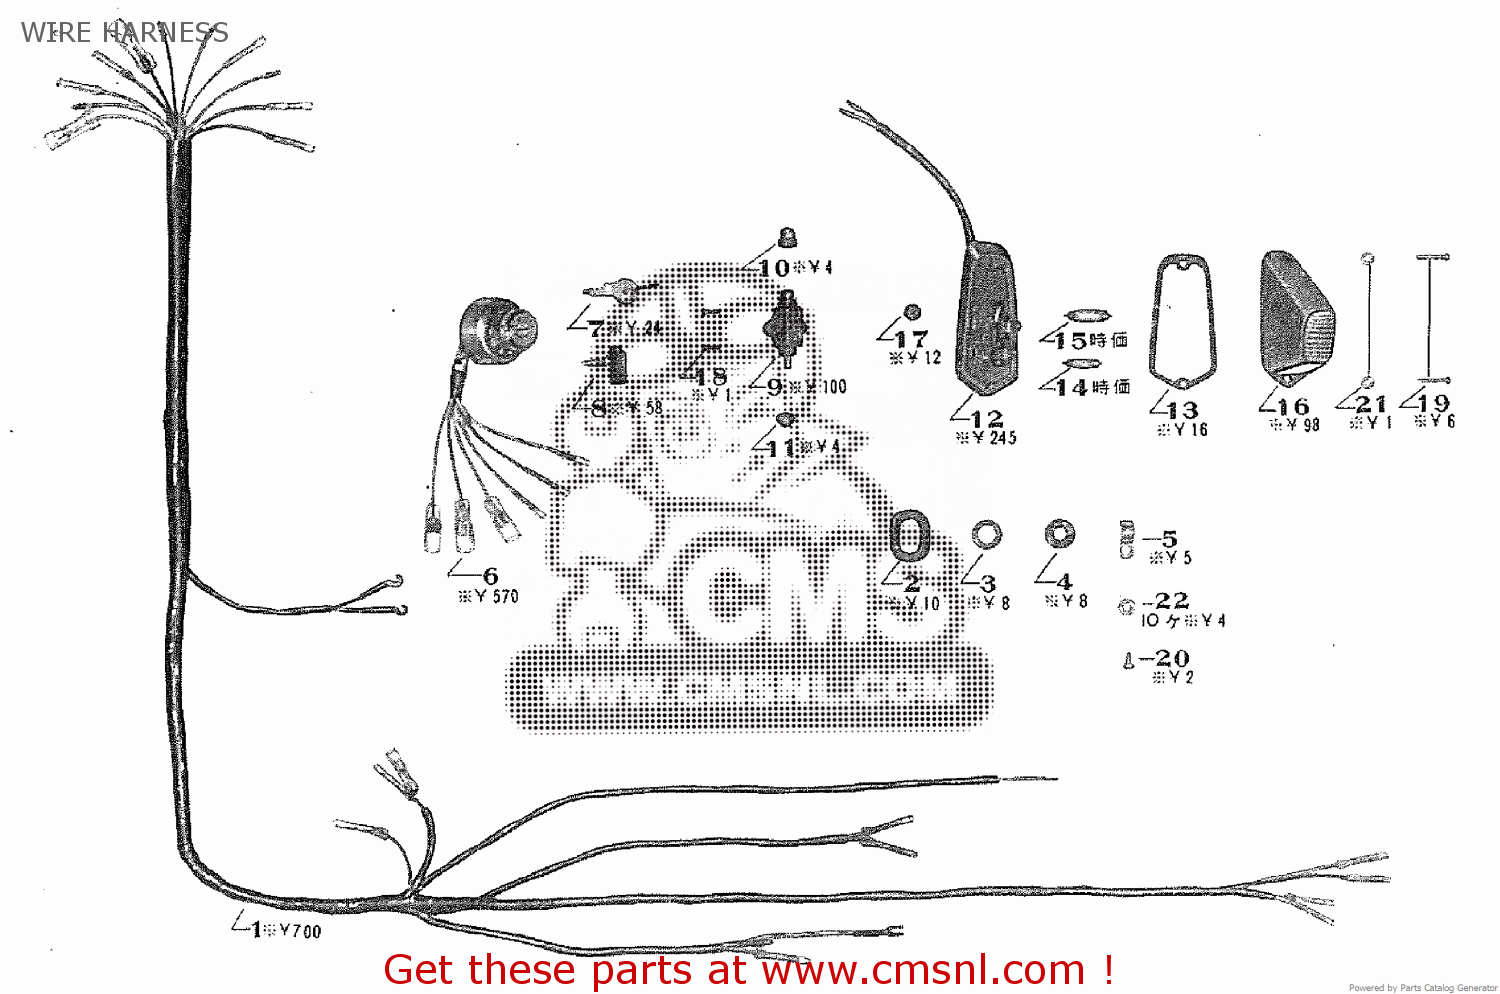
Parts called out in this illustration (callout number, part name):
1	WIRE HARNESS ASSY.
2	RUBBER PIPE BUSH
3	CORD CLIP BUSH
4	RUBBER PIPE BUSH
5	WIRE HARNESS CLIP BAND
6	MAIN SWITCH BODY
7	MAIN SWITCH PRESS KEY
8	MAIN SWITCH MASCOT KEY
9	STOP LAMP SWITCH ASSY.
10	RUBBER CAP (A)
11	RUBBER CAP (B)
12	TAIL STOP LAMP ASSY.
13	LENS SET PACKING
14	TAIL LAMP VALVE
15	STOP LAMP VALVE
16	TAIL STOP LAMP LENS
17	BODY RUBBER BUSH
18	4X12 CROSS SCREW
19	4X20 CROSS SCREW
20	6X10 CROSS SCREW
21	4MM PLANE WASHER
22	6MM SPRING WASHER
